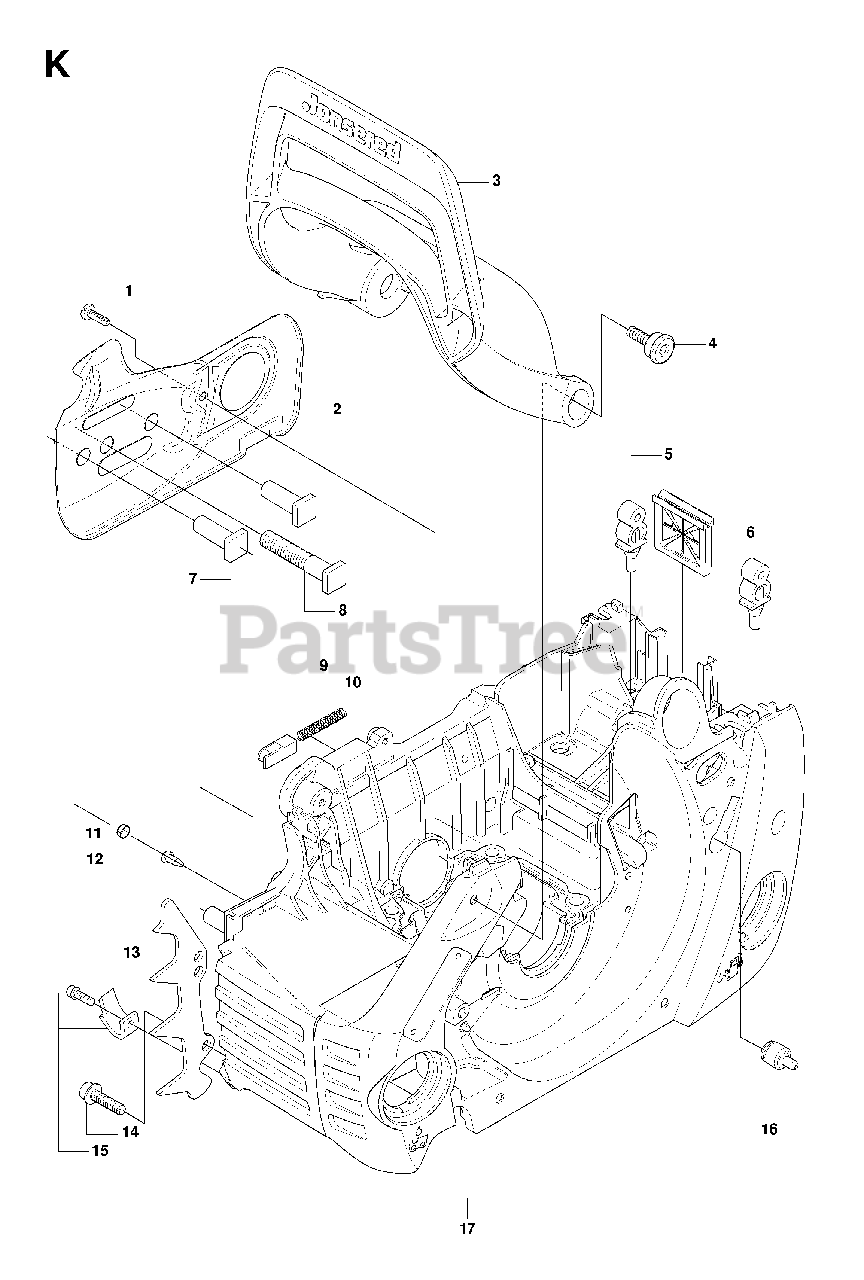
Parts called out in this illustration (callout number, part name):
3	HAND GUARD
4	SCREW, HAND GUARD
7	GUIDE BOLT (X2)
10	LOCK SPRING
11	PLUG
12	VALVE-CHECK (DUCKBILL)
13	FELLING DOG
14	SCREW
15	CHAIN CATCHER
16	FUEL TANK VENT
17	CRANKCASE
